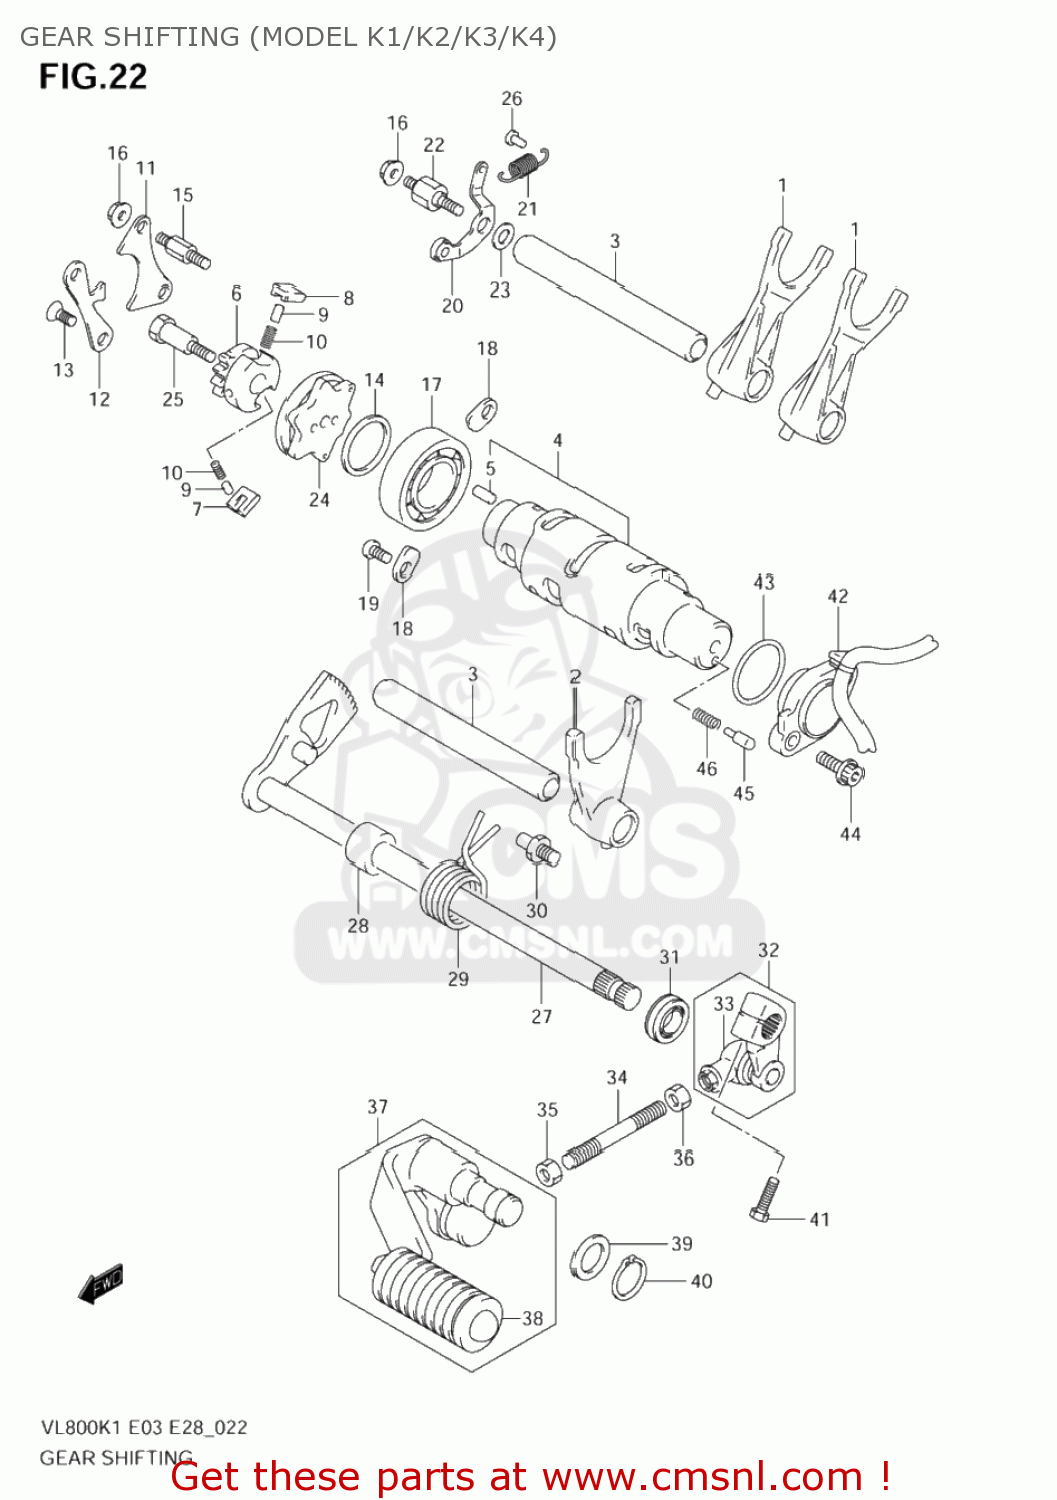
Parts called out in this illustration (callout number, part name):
1	FORK,GEAR SHIFT NO.1
2	FORK,GEAR SHIFT NO.2
3	SHAFT,GEAR SHIFT FORK(L:115)
4	CAM,GEAR SHIFT
5	PIN
6	GEAR,GEAR SHIFT CAM DRIVEN
7	PAWL,GEAR SHIFT NO.1
8	PAWL,GEAR SHIFT NO.2
9	PIN(5X8)
10	SPRING
11	LIFTER,GEAR SHIFT POLE
12	GUIDE,GEAR SHIFT CAM
13	SCREW(6X12)
14	WASHER(25X32X3)
15	BOSS,SHIFT POLE LIFTER
16	NUT
17	BEARING(25X47X8)
18	RETAINER
19	SCREW(6X12)
20	STOPPER,GEAR SHIFT CAM
21	SPRING
22	SUPPORT,CAM STOPPER ARM
23	WASHER
24	PLATE,GEAR SHIFT CAM
25	PIN,SHIFT CAM DRIVEN GEAR
26	RIVET
27	SHAFT,GEAR SHIFT
28	SPACER(12X20X15.3)
29	SPRING
30	STOPPER,GEAR SHIFT ARM
31	OIL SEAL
32	ARM,GEAR SHIFT SHAFT
33	COVER,DUST
34	ROD,GEAR SHIFT LINK
35	NUT
36	NUT
37	LEVER ASSY,GEAR SHIFT
38	RUBBER,GEAR SHIFT PEDAL
39	WASHER(14.5X22X1.6)
40	CIRCLIP
41	BOLT
42	BASE ASSY, GEAR SHIFT TERM
43	O RING(D:2.4,ID:25.7)
44	BOLT
45	PIN(5X15.5)
46	SPRING
